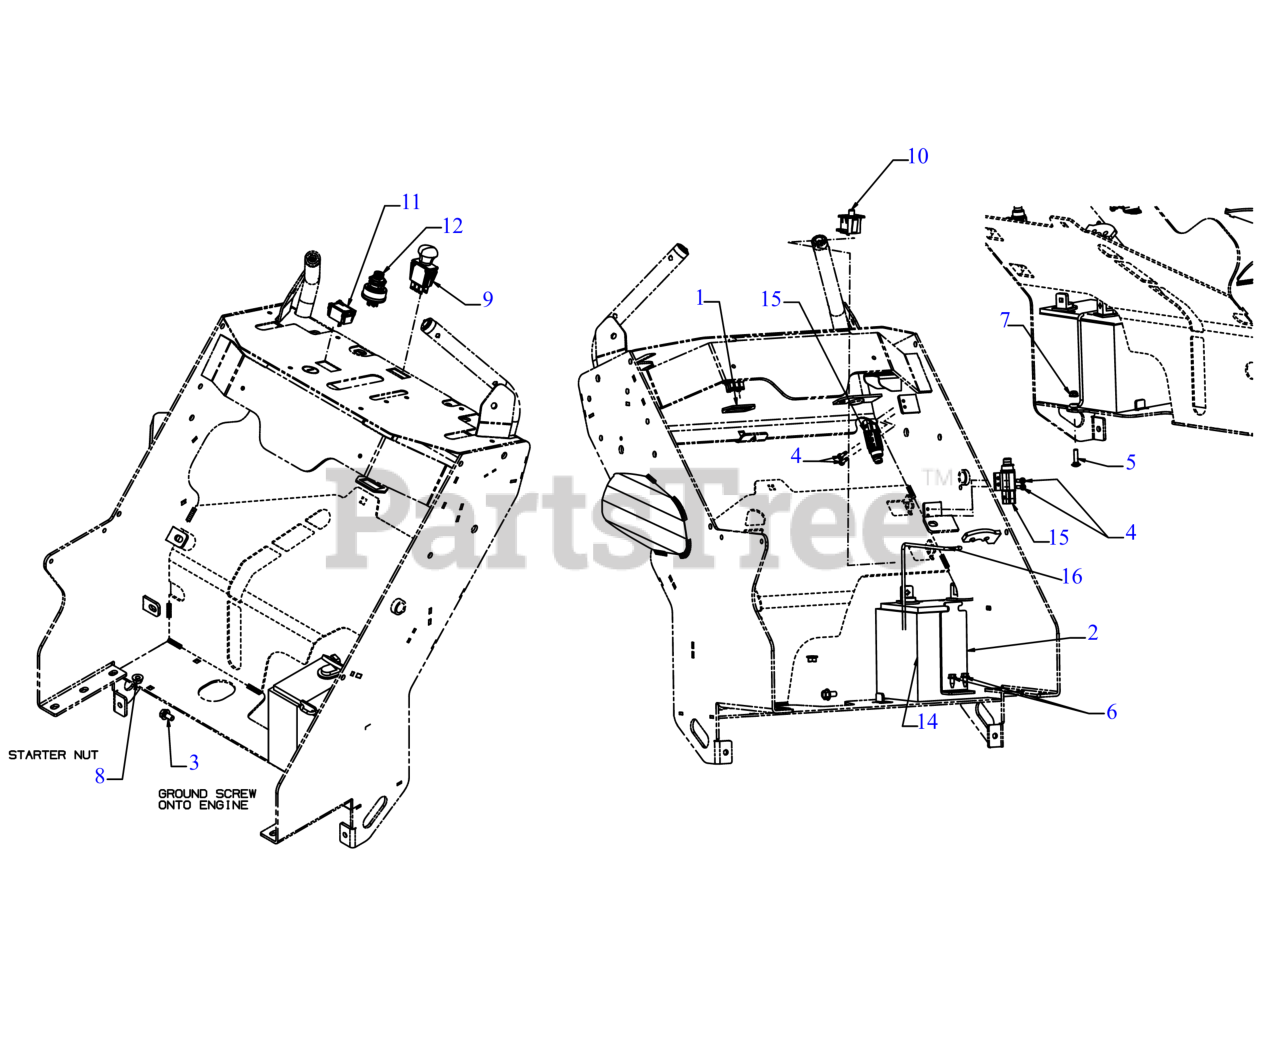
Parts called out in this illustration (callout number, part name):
1	BRACKET-PTO SWITCH
2	BATTERY RETAINING BRACKET
3	SCREW M8 x 1.25 x 16MM GR8.8
4	SCREW (10-24X.75:PH:TAP:T25:GR5)
5	SCREW 1/4-20 x 1 GR5
6	SCREW 1/4-20X.625
7	FLANGE LOCK NUT
8	HEX FLANGE NUT
9	PTO SWITCH (BLACK KNOB) TEXT SYM
10	SEAT SWITCH N/C,N/C
11	HOURMETER
12	KEY SWITCH (3 POSITION)
14	BATTERY (230 CCA AGM U1-280)
15	SEALED PLUNGER SWITCH
16	BATTERY SUPPORT ROD
